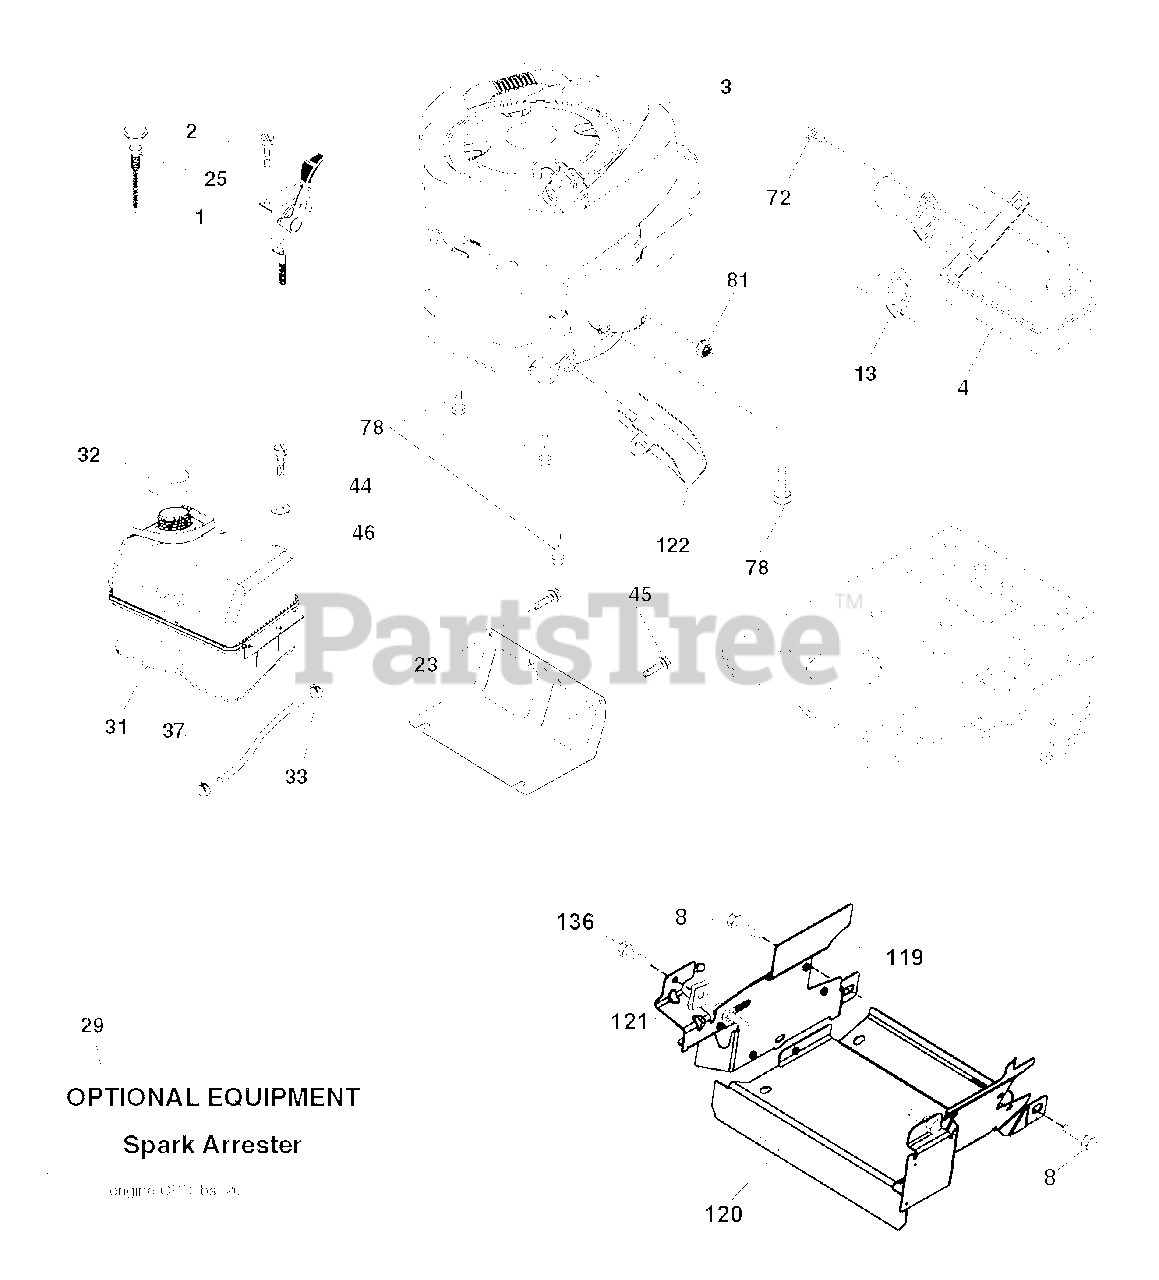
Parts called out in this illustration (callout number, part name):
1	CONTROL.THROTTLE/CHOKE.BLACK
2	SCREW
3	Husqvarna TBD
4	MUFFLER.LT.BRIGGS.14HP.IC/OHV
8	BOLT, 5/16-18 X 1 3/4
13	REPL BY 532 27 22-93
23	SHIELD.BROWNING.DBR.GUARD
25	KNOB.ERGO.EXTENDED.RED (1 2)
29	KIT.SPARK ARRESTOR 794945 B&S
31	TANK.FUEL.FRT.N/CAP.2.0GAL.DAP
32	CAP ASM.FUEL.2.25"FR.
33	HOSE CLAMP
37	LINE.FUEL.20
44	SCREW HEXWSHR 1/4-20X3/4
45	SCREW, 3/8-16X3/4
72	SCREW.SOCKET HD.5/16-1
78	SCREW.3/8-16
81	NUT
119	LENKRAD
120	GUARD 532199767
122	EXTENSION DRAIN OIL
136	SCREW.1/4-20X5/8
